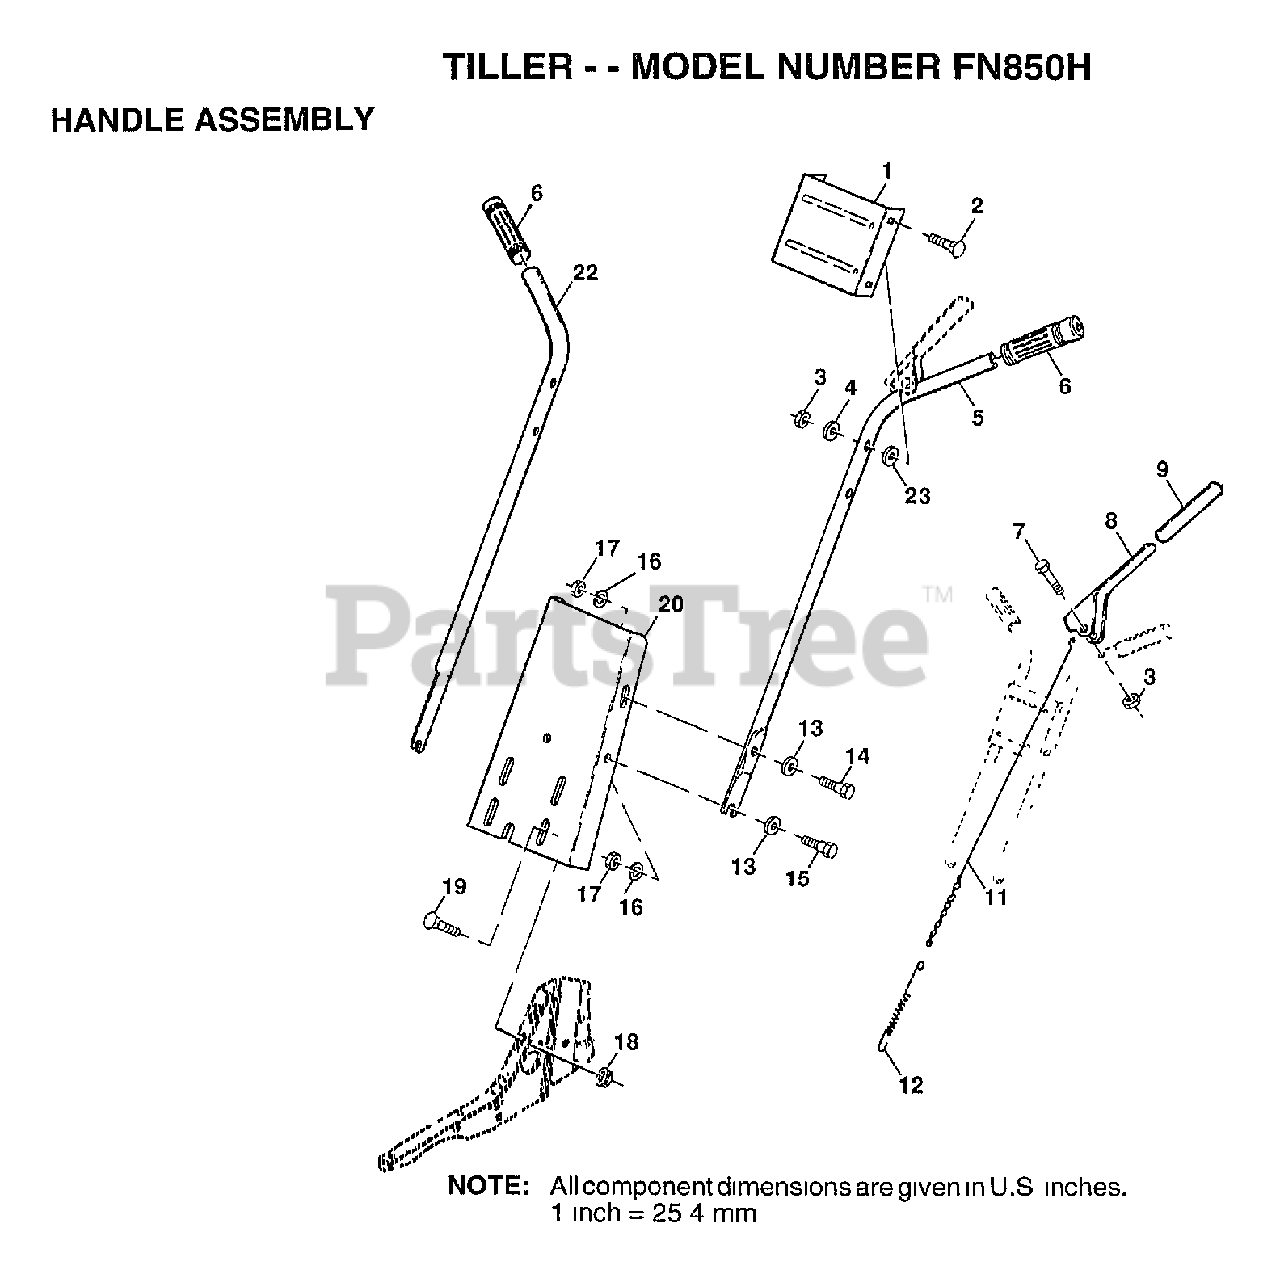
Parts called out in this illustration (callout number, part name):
1	HANDLE BRKT
2	BOLT
4	WASHER
5	HANDLE LH
7	BOLT.HEX.5/16-1.5
8	LEVER.CONTROL.TINE
9	GRIP T
12	SPRING EXT TI
13	WASHER
15	BOLT
16	LOCKWASHER
17	NUT.HEX.5/16-18
18	NUT
19	BOLT
20	PANEL. HANDLE
22	HANDLE RH
23	WASHER
